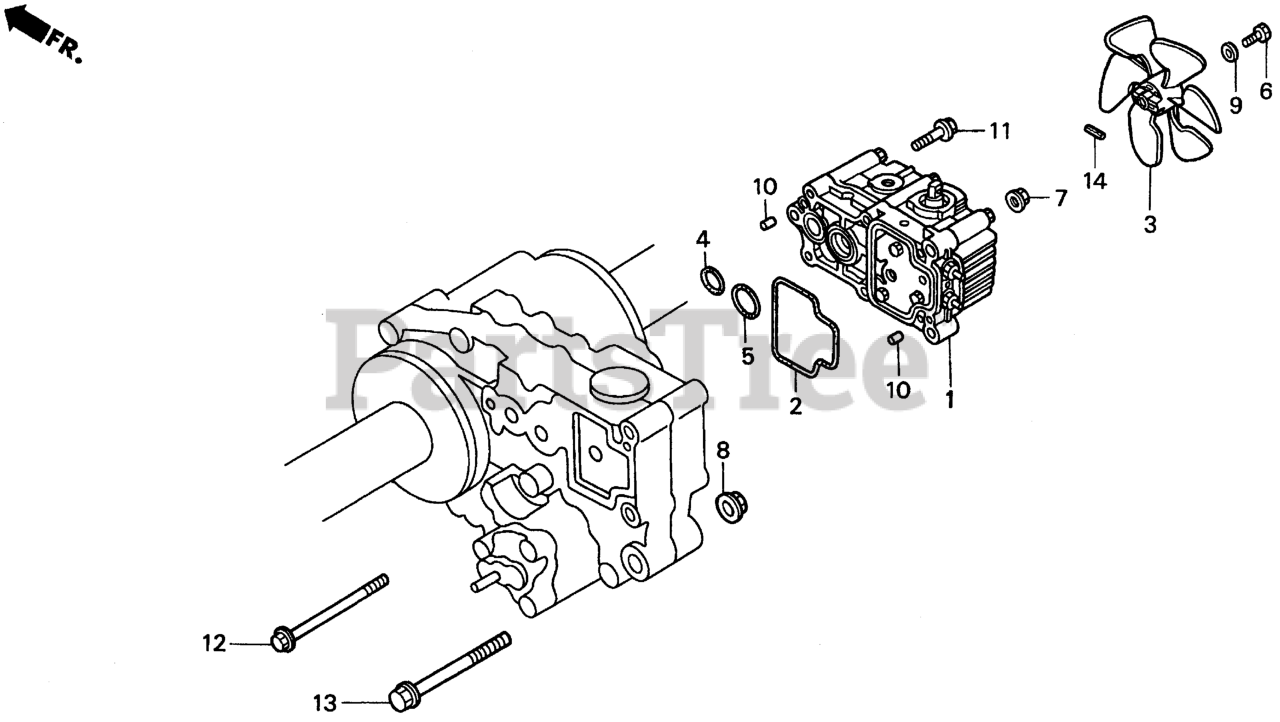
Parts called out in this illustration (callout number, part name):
1	TRANSMISSION SUB-ASSY. (H.S.T.)
2	O-RING, CHANGE PUMP
3	FAN, TRANSMISSION COOLING
4	O-RING (21.8X2.4)
5	O-RING (28.5X2.0)
6	BOLT, HEX. (5X10)
7	NUT, FLANGE (8MM)
8	NUT, FLANGE (12MM)
9	WASHER, PLAIN (5MM)
10	PIN A, DOWEL (6X10)
11	BOLT, FLANGE (8X35)
12	BOLT, FLANGE (8X110)
13	BOLT, FLANGE (12X80)
14	ROLLER (3X19.8)
